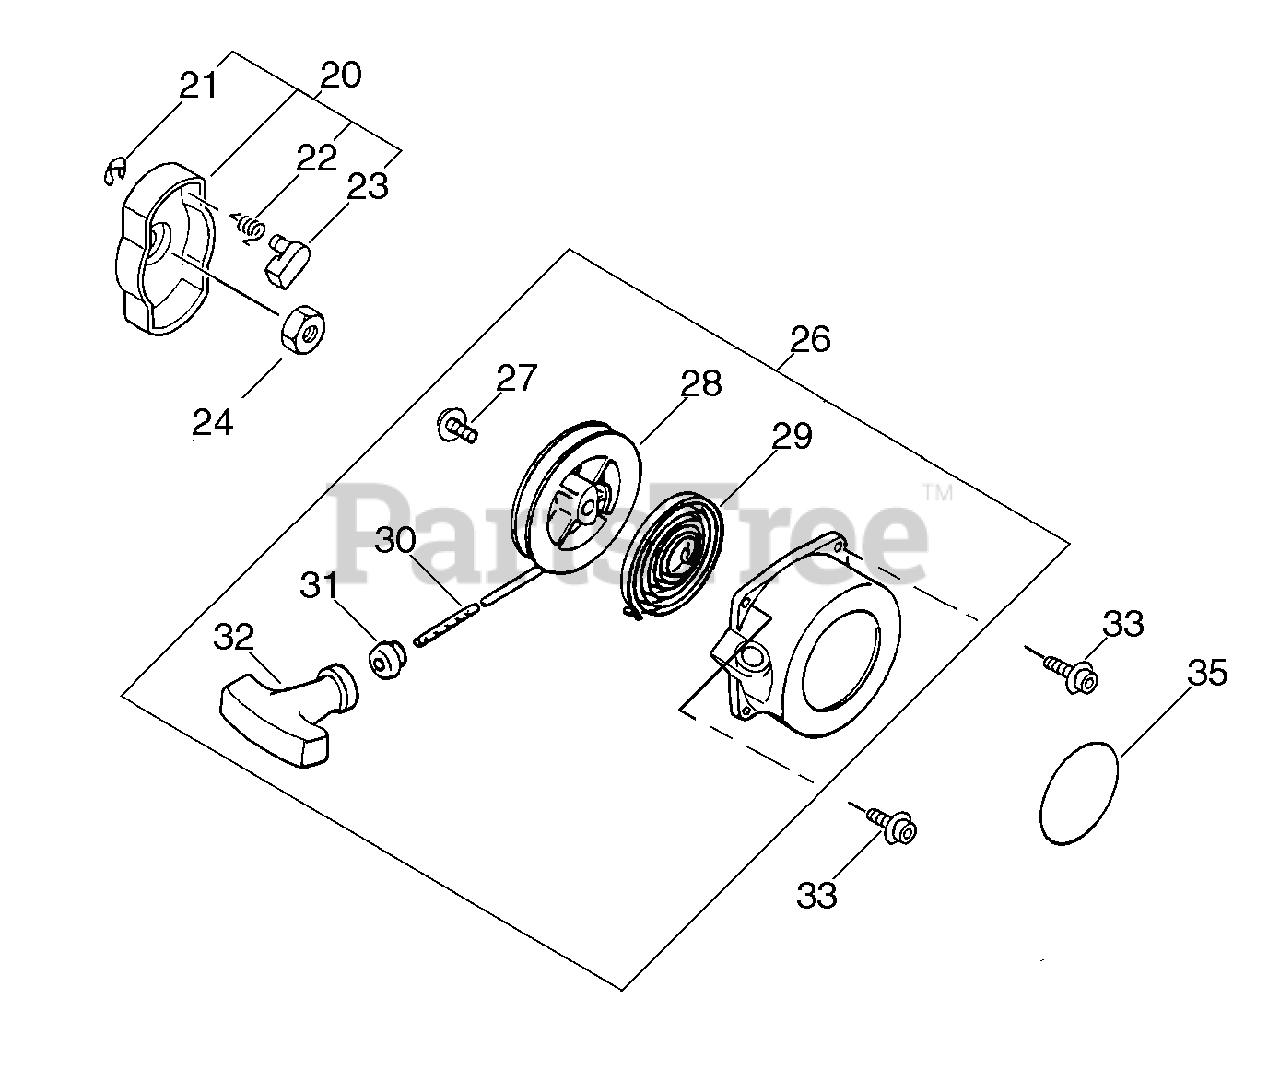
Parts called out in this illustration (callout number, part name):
20	STARTER PAWL ASSY
21	RING, RETAINING - 4
22	SPRING, RETURN
23	PAWL, STARTER
26	STARTER ASSY
28	REEL, ROPE
29	SPRING, REWIND
30	ROPE, STARTER 3.8×1150
31	GUIDE, ROPE
32	GRIP, STARTER
33	SCREW - 5X20
35	LABEL - ECHO
